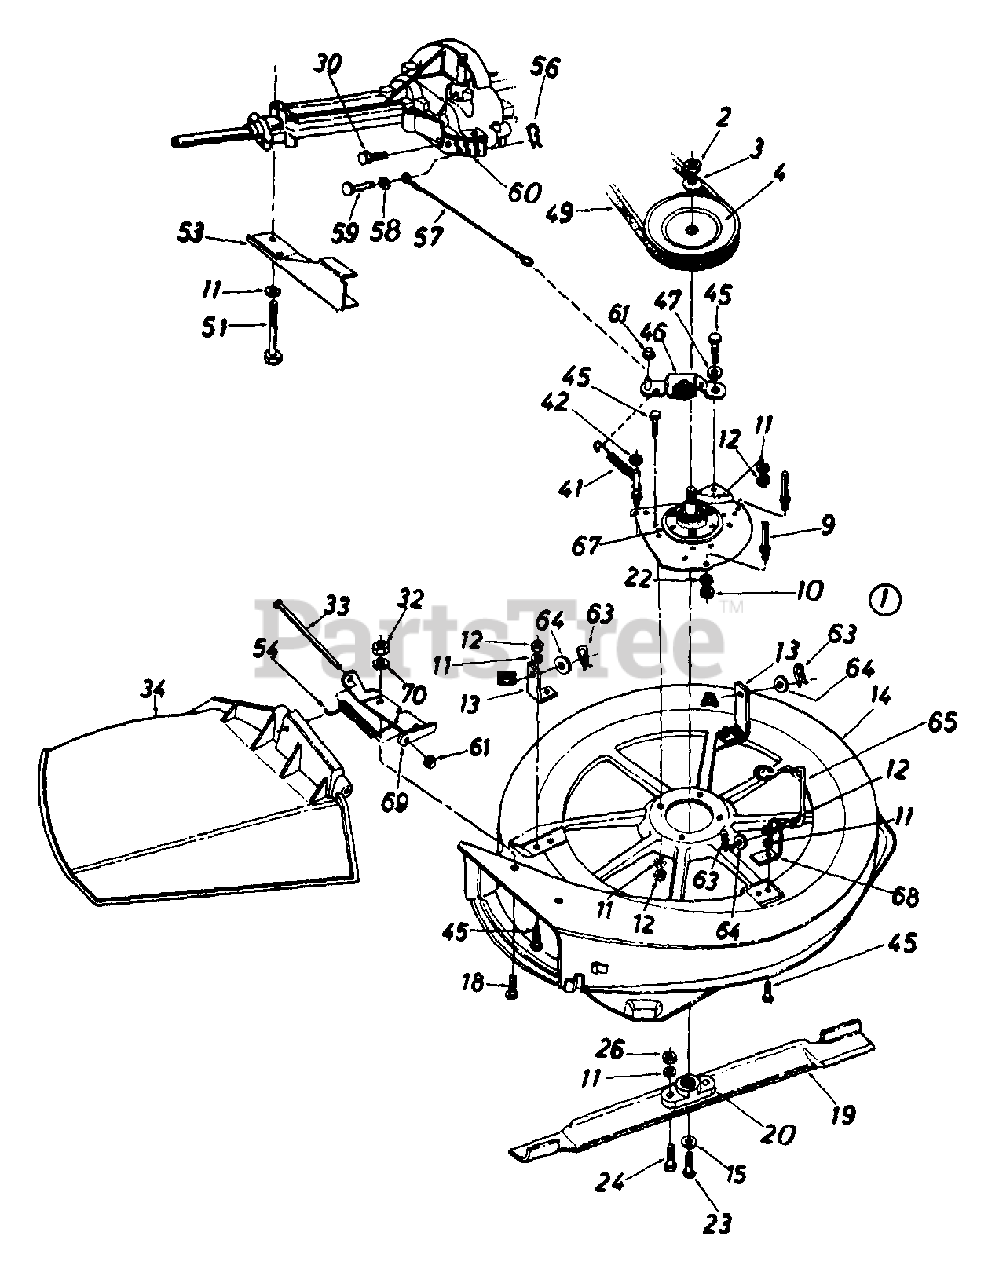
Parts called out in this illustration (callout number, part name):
1	30" S.O. Deck Ass'y. Comp.
2	Hex Jam Nut 5/8-18 Thd.
3	Bell-Wash..630" I.D. x 1.25"
4	5/8 V-Pulley.75" I.D. x 7"
9	Stud 3/8-16 x 2.75" Lg.
10	Hex Jam Nut 3/8-16 Thd.
11	L-Wash. 5/16" I.D.
12	Hex Nut 5/16-18 Thd.
18	Truss Mach. Scr. 1/4-20 x .75" Lg.
19	30" High Lift Blade
20	Blade Adapter
22	L-Wash. 3/8" I.D.
23	Hex Bolt 3/8-24 x 1.0
24	Hex Bolt 5/16-24 x 1.0" Lg.
26	Hex Nut 5/16-24 Thd.
30	Hex Bolt 1/4-20 x .50" Lg.
32	Hex Nut 1/4-20 Thd.
33	Hinge Pin
34	Chute Ass'y. Comp.
41	Extension Spring .5" O.D, x 3.2" Lg.
42	Push Speed Nut
45	Hex Bolt 5/16-18 x .75"
46	Blade Brake Brkt. Ass'y.
47	Shoulder Spacer .500" Dia.
49	V-Belt
51	Hex Bolt 5/16-18 x 2.75"
56	Int. Cot. Pin 5/16" Dia.
57	Brake Cable 9.75" Lg.
58	Fl-Wash..281" I.D. x .50"
59	Clevis Pin 1/4" Dia.
60	Lower Inside Belt Guard
61	Cap Speed Nut 1/4" Rod
63	Int. Cotter Pin 1/2" Dia.
64	Fl-Wash..531" I.D. x .930"
65	Deck Link 3.9" Lg.
67	Blade Spindle Ass'y. Comp.
68	Weld Bracket
69	Hinge Mtg. Brkt.
70	Bell-Wash. 1/4" I.D.
